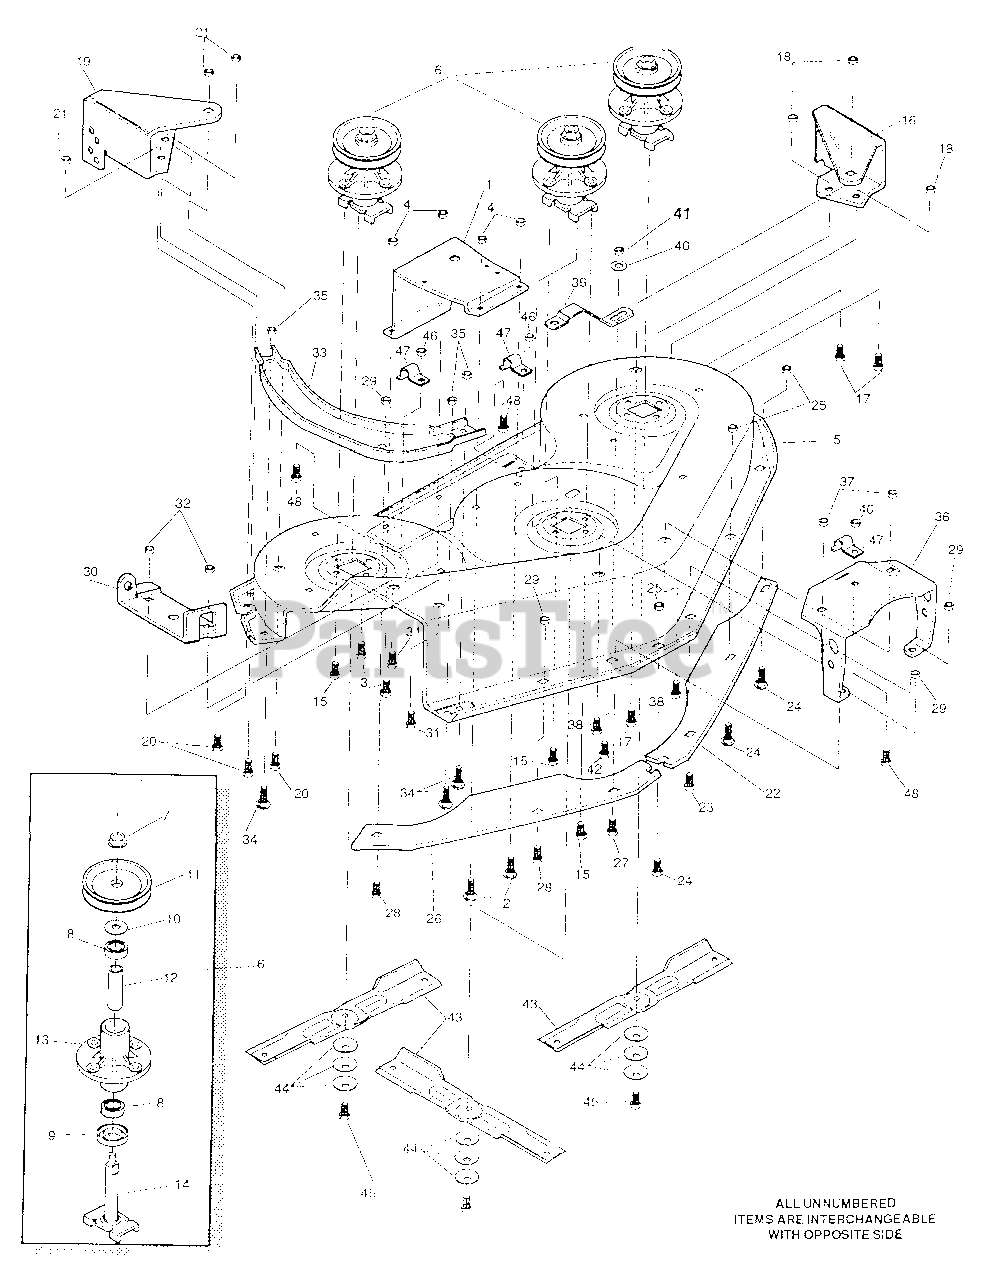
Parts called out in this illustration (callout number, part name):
1	Support Bracket 46"
2	Bolt, 5/16-18 x 5/8 In. Carr.
3	Screw, 5/16-18 x .63 In.
4	Nut, 5/16-18 Centerlock
5	Mower Deck 46" Sus.SD
6	Quill Assy.
7	Nut, 7/16-20 Wide Fl. Lock
8	Bearing, Ball
9	Dust Shield
11	Quill Pulley
12	Spacer, LH & RH Quill
13	Casting LH
14	Saddle & Shaft Assy.
15	Screw, 5/16-18 x .87 Taptite
16	Bracket Gauge Wheel L.H.
17	Screw, 5/16-18 x .63 In.
18	Nut, 5/16-18 Centerlock
19	Bracket Gauge Wheel R.H.
20	Screw, 5/16-18 x .631 n.
21	Nut, 5/16-18 Centerlock
22	Baffle 46" Deck
23	Screw, 5/16-18 x.63 In.
24	Carriage Bolt, 5/16-18 x 5/8 In.
25	Nut, 5/16-18 Centerlock
26	Baffle RH 46" Deck
27	Screw, 5/16-18 x 5/8 In.
28	Carriage Bolt, 5/16-18 x 5/8 In.
29	Nut, 5/16-18 Centerlock
30	Bracket Chute Mount
31	Screw, 5/16-18 x 5/8 In.
32	Nut, 5/16-18 Centerlock
33	Brace, Skid
34	Carriage Bolt, 5/16-18 x 5/8 In.
35	Nut, 5/16-18 Centerlock
36	Lift Support Bracket
37	Nut, 5/16-18 Centerlock
38	Screw, 5/16-18 x 5/8 In.
39	Support Bracket
40	Flatwasher
41	Nut, 5/16-18 Centerlock
42	Screw, 5/16-18 x 5/8 In.
43	Blade, 16/13 High-Lift
44	Washer, Bellville
45	Screw, 3/8-24 x 1.00 Nylock
46	Nut, 5/16-18 Centerlock
48	Screw, 5/16-18 x 5/8 In.
